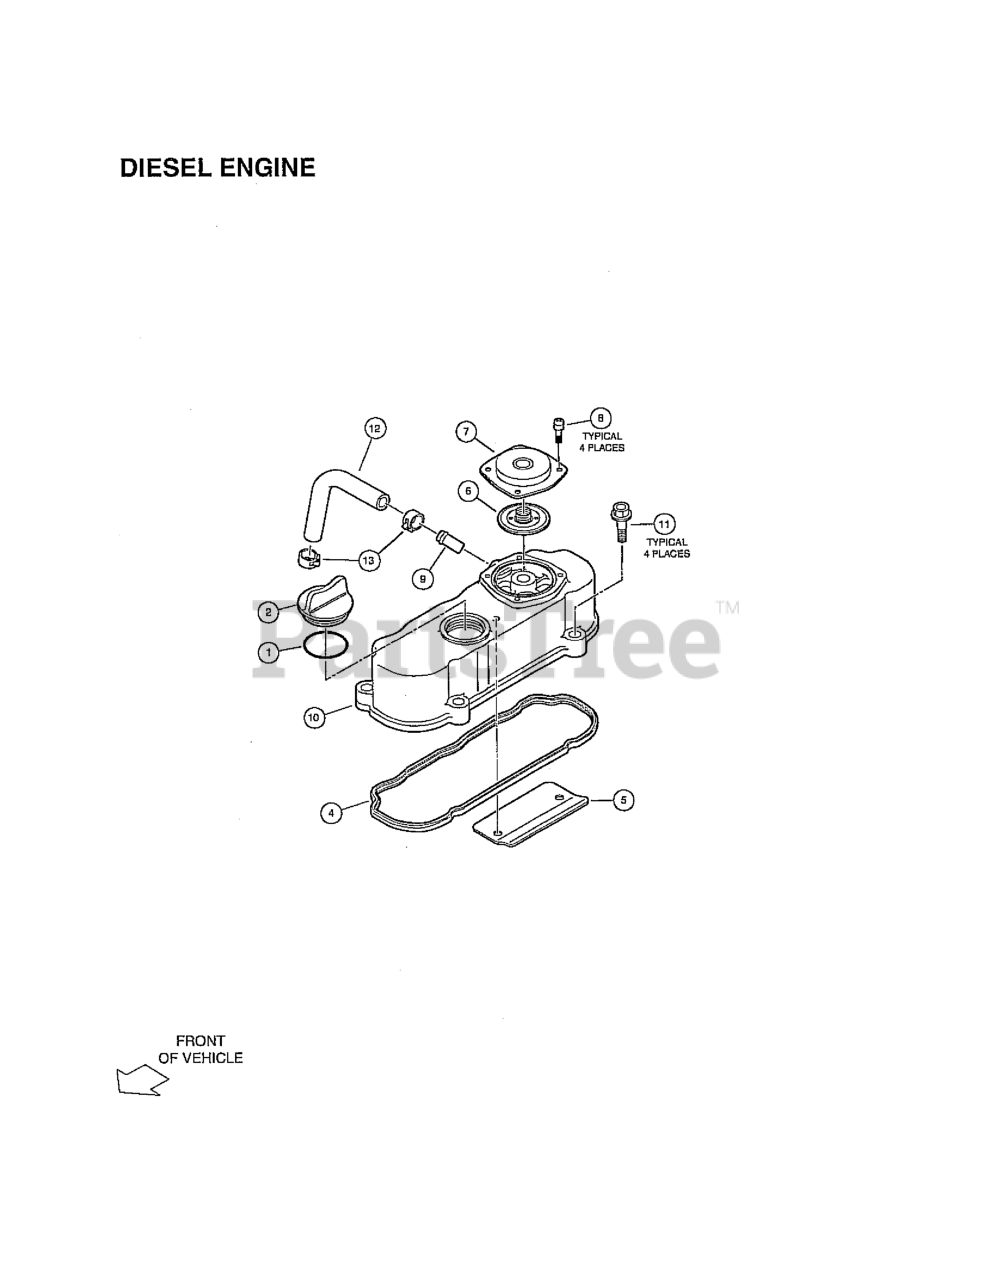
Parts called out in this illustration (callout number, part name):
1	O RING, 30X36
2	PLUG, OIL FILLER
3	ASSY-CYL HEAD COVER
4	GASKET-HEAD COVER
5	SHIELD-BREATHER
6	VALVE-BREATHER
7	COVER-BREATHER
8	SCREW-BREATHER
9	PIPE-BREATHER
11	BOLT-CYL HEAD COVER
13	CLAMP-BRTHR TUBE
